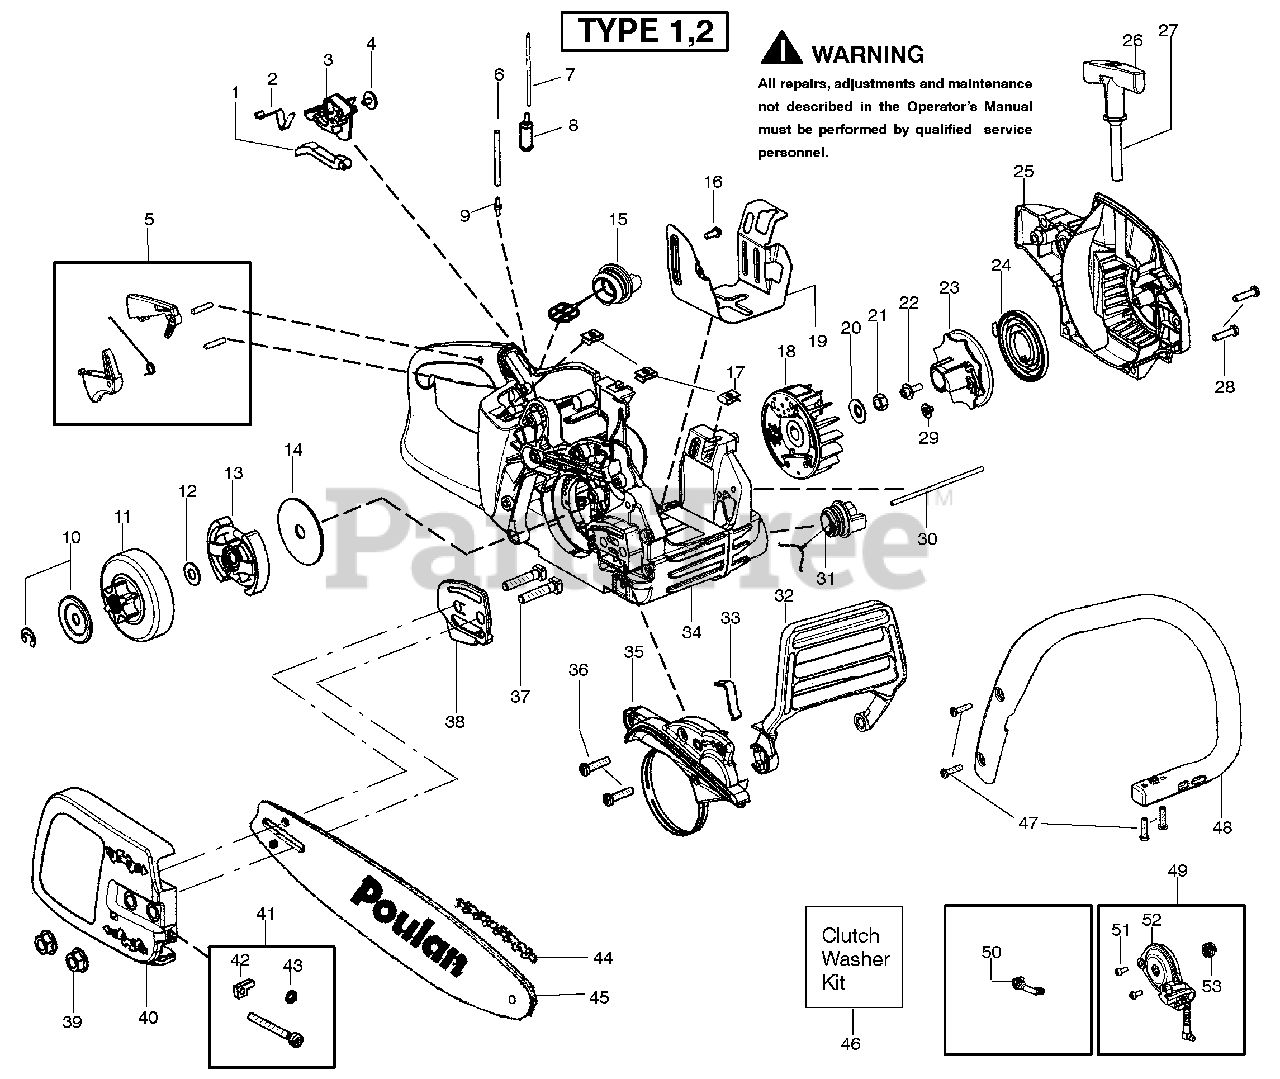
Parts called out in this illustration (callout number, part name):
1	Knob-Choke
2	Spring-Ign. Switch
3	Lever-Ign. Switch
5	Kit-Trigger/Lockout
6	Kit-Fuel Line
7	Kit-Fuel Line
8	Assy-Fuel Pick Up
9	Fitting-Fuel line
10	Kit-Clutch Washer
11	Assy-Clutch Drum 3/8"
12	Kit-Clutch Washer
13	Assy-Clutch
14	Washer-Large Clutch
15	Assy-Fuel Cap w/ret
17	Nut-"U" type speed
18	Assy-Flywheel
19	Shield-Heat
20	Washer-Flywheel
21	Nut-Flywheel
22	Screw
23	Pulley-Starter
24	Spring-Starter
25	Housing-Fan
26	Handle-Starter
27	Kit-Rope
30	Assy-Oil Vent
31	Assy-Oil Cap w/ret.
32	Handguard
33	Spring-Handguard
34	Assy-Chassis
35	Kit-Chainbrake
37	Bolt-Bar
38	Plate-Bar
40	Assy-Clutch Cover
41	Kit-Bar Adjust
42	Pin-Bar Adjust
43	Retainer-Bar Adjust
44	Accy-14" Chain
45	Accy-14" Bar
46	Kit-Clutch Washer
48	Handle-Front
49	Kit-Oil Pump
50	Assy-Oil Pick Up
52	Assy-Oil Pump
53	Gear-Worm
